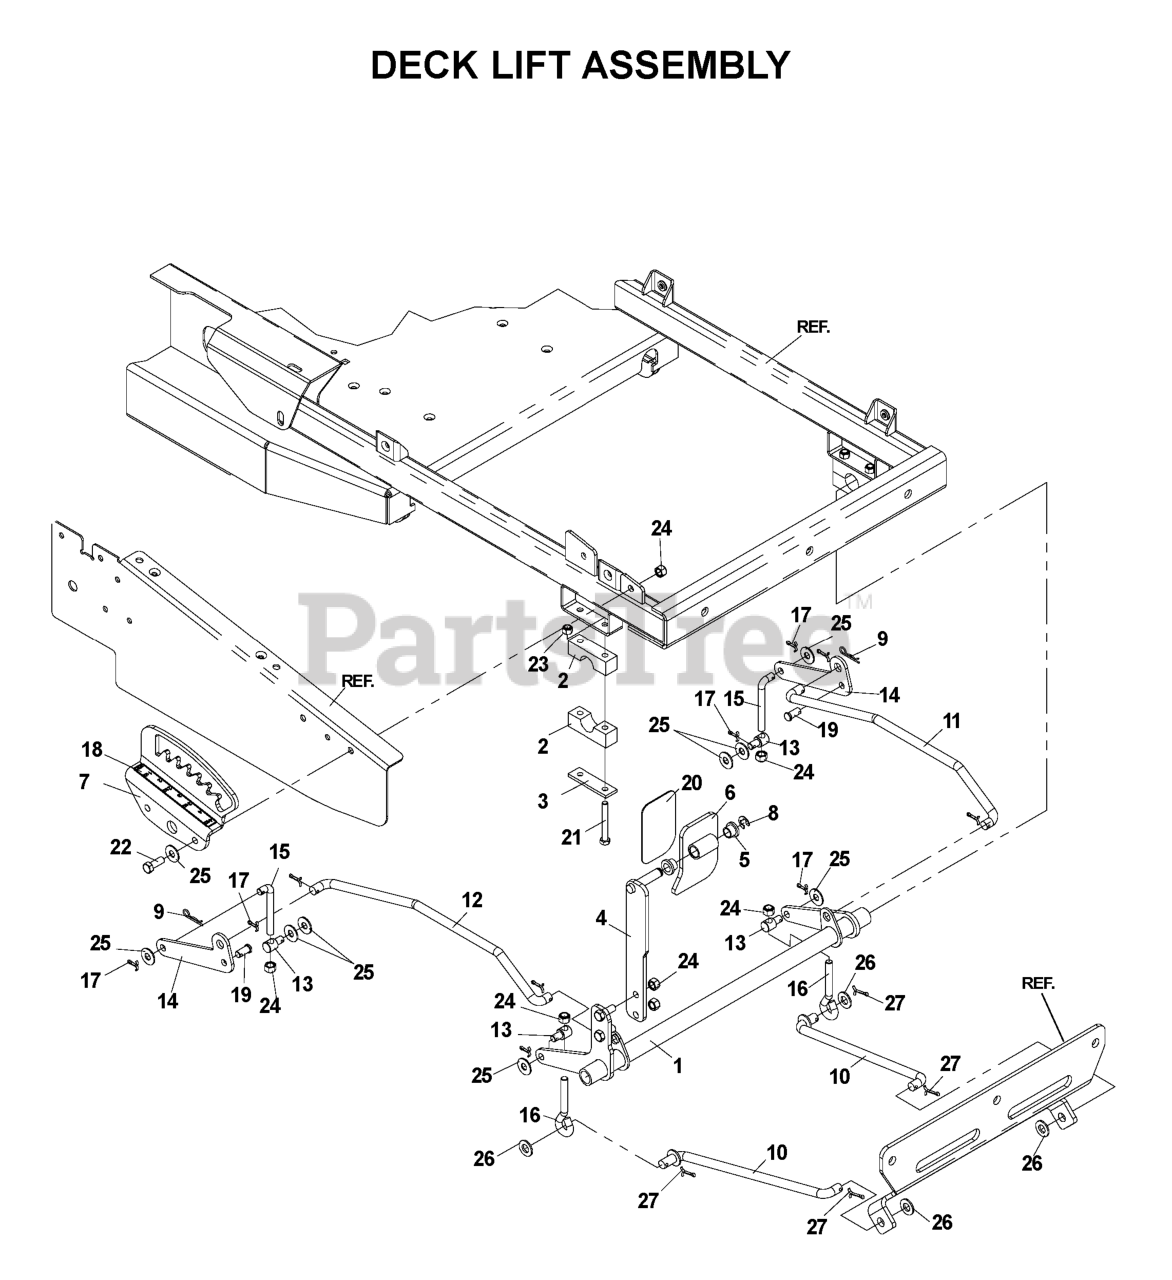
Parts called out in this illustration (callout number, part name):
1	CROSS SHAFT WELDMENT
2	PILLOW BLOCK
3	REINFORCEMENT BAR
4	LIFT ARM WELDMENT
5	BUSHING, FLANGED NYLON
6	FOOT PEDAL WELDMENT
7	HEIGHT PLATE
8	E-RING 1/2 (2 2)
9	HAIRPIN #2
10	STRUT LINKAGE
11	LIFT LINKAGE-LH
12	LIFT LINKAGE-RH
14	REAR BELLCRANK
15	LIFT LINKAGE
17	RP_COTTER PIN 1/8 X 3/4
18	DECAL, CUTTING HEIGHT
19	CLEVIS PIN
21	BOLT 5/16C X 2 1/2
22	HCS 3/8C X 1 1/4 GR5
23	NUT 5/16 NYLOC
24	NUT 3/8-16 NYLOC
25	WASHER 3/8 FLAT
26	WASHER 1/2" FLAT
27	COTTER PIN
